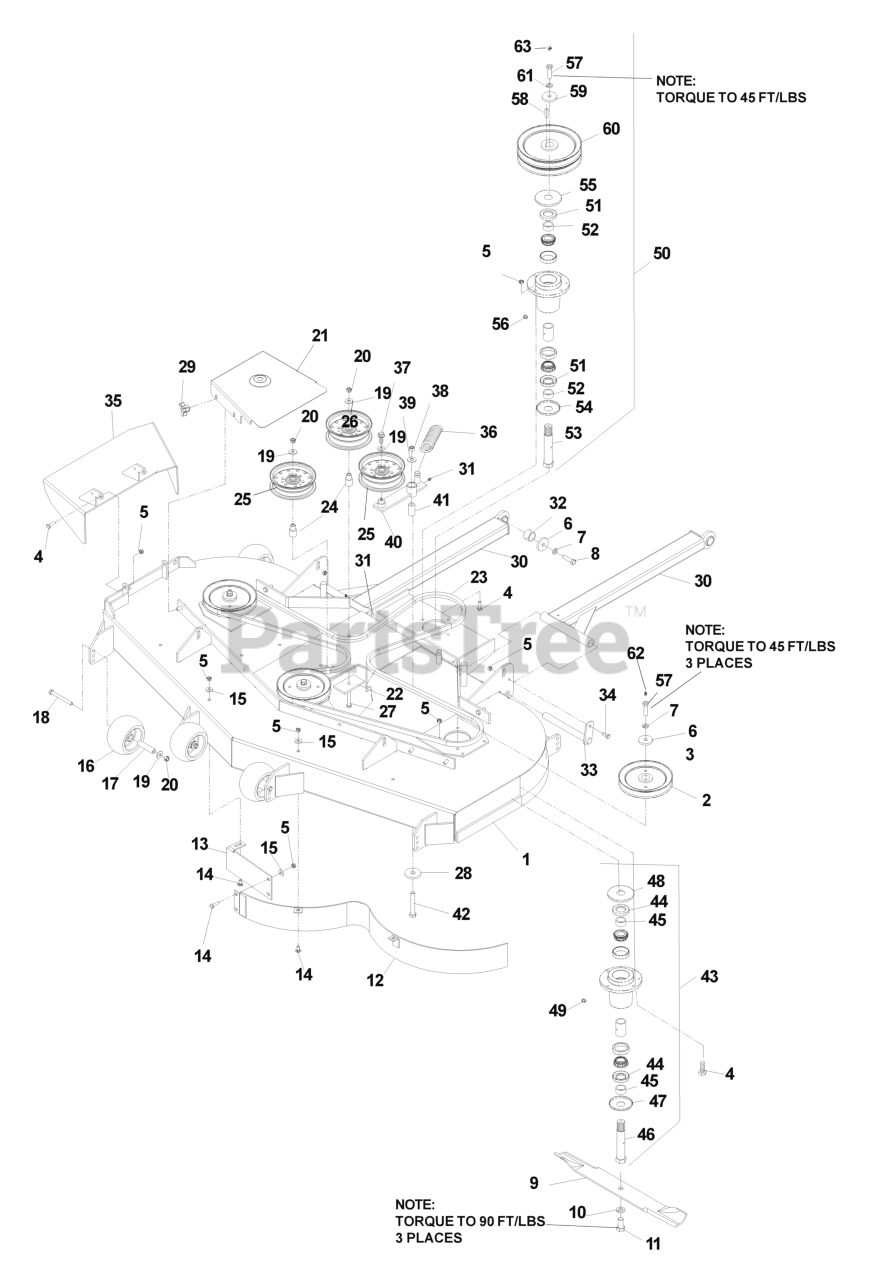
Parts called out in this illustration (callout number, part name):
1	DECK W/DECALS 61" HUS WSL
2	RP PULLEY - 61"
4	HCS 5/16C X 1
5	NUT 5/16C CENTERLOCK
6	SPINDLE WASHER
7	WASHER 7/16 LOCK
8	HCS 7/16F X 1 1/2
9	BLADE OEM 21" (61" DECK)
10	LOCKWASHER 5/8
11	HCS 5/8F X 1 1/4
12	MAIN BAFFLE - 61" BLK
13	CENTER BAFFLE - 61
14	CARRIAGE BOLT 5/16C X 5/8"
15	WASHER 5/16 FLAT
16	ANTI-SCALP ROLLER
18	HCS 3/8C X 3 1/2
19	WASHER 3/8 FLAT
20	NUT 3/8C CENTERBLOCK
21	BELT SHIELD 61" RIGHT
22	SUPPORT PLATE
23	BELT, DECK
24	IDLER BUSHING
25	IDLER PULLEY
26	IDLER PULLEY (TALL)
27	HCS 3/8C X 2 1/2
28	WASHER, SUPPORT
29	KNOB, THREE PRONG
30	STRUT WELDMT, L.H.
31	ZERK
32	SPACER, STRUT
33	PIN WELDMENT
34	HCS 5/16C X 3/4
35	CHUTE 61 ORANGE
36	DECK SPRING
37	4CS 3/8C X 1 SERRATED HEAD
38	NUT 1/2-13 HEX NYLOC ZD
39	WASHER 1/2 FLAT
41	PIVOT BUSHING
42	HCS 1/2C X 3 1/4
43	SPINDLE ASSY - 52/61"
44	SHAFT SEAL
46	52/61 SPINDLE - SPLINED SHAFT
47	BOTTOM DUST CAP
48	TOP DUST CAP
49	PLUG-VENTED
50	JACKSHAFT ASSY LOWER
51	SHAFT SEAL
53	JACKSHAFT SPINDLE
54	BOTTOM DUST CAP
55	TOP DUST CAP
56	PLUG-VENTED
57	DRILLED BOLT 7/16-20 X 1 1/2"
58	KEY 1/4 SQ X 1 1/8
59	SPINDLE WASHER
60	SHEAVE WSL
61	WASHER 7/16 LOCK
62	ZERK
